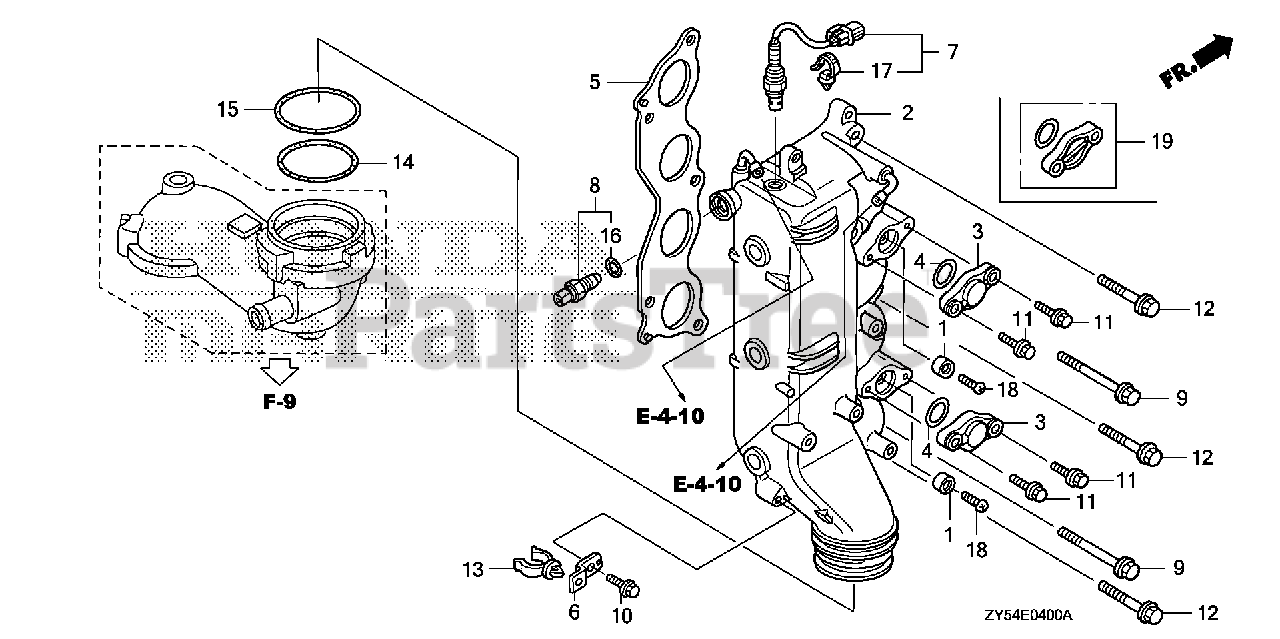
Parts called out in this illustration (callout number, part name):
1	METAL, ANODE
2	MANIFOLD, EX. *NH8* (DARK GRAY)
3	COVER, EX. MANIFOLD *NH8* (DARK GRAY)
4	O-RING (37X2.4)
5	GASKET, EX. MANIFOLD
6	BRACKET, WATER TUBE CLAMP
7	SENSOR, LAF
8	SENSOR ASSY., WATER TEMPERATURE
9	BOLT, FLANGE (10X75)
10	BOLT, FLANGE (6X14)
11	BOLT, FLANGE (6X22)
12	BOLT, FLANGE (10X45)
13	CLAMP B, WATER TUBE
14	O-RING (76.4X3.1)
15	O-RING (79.8X3.1)
16	O-RING (9.5X1.9)
17	CLIP, HARNESS BAND (145.2MM) (NATURAL)
18	SCREW, PAN (6X18)
19	COVER KIT, EX. MANIFOLD *NH8* (DARK GRAY)
